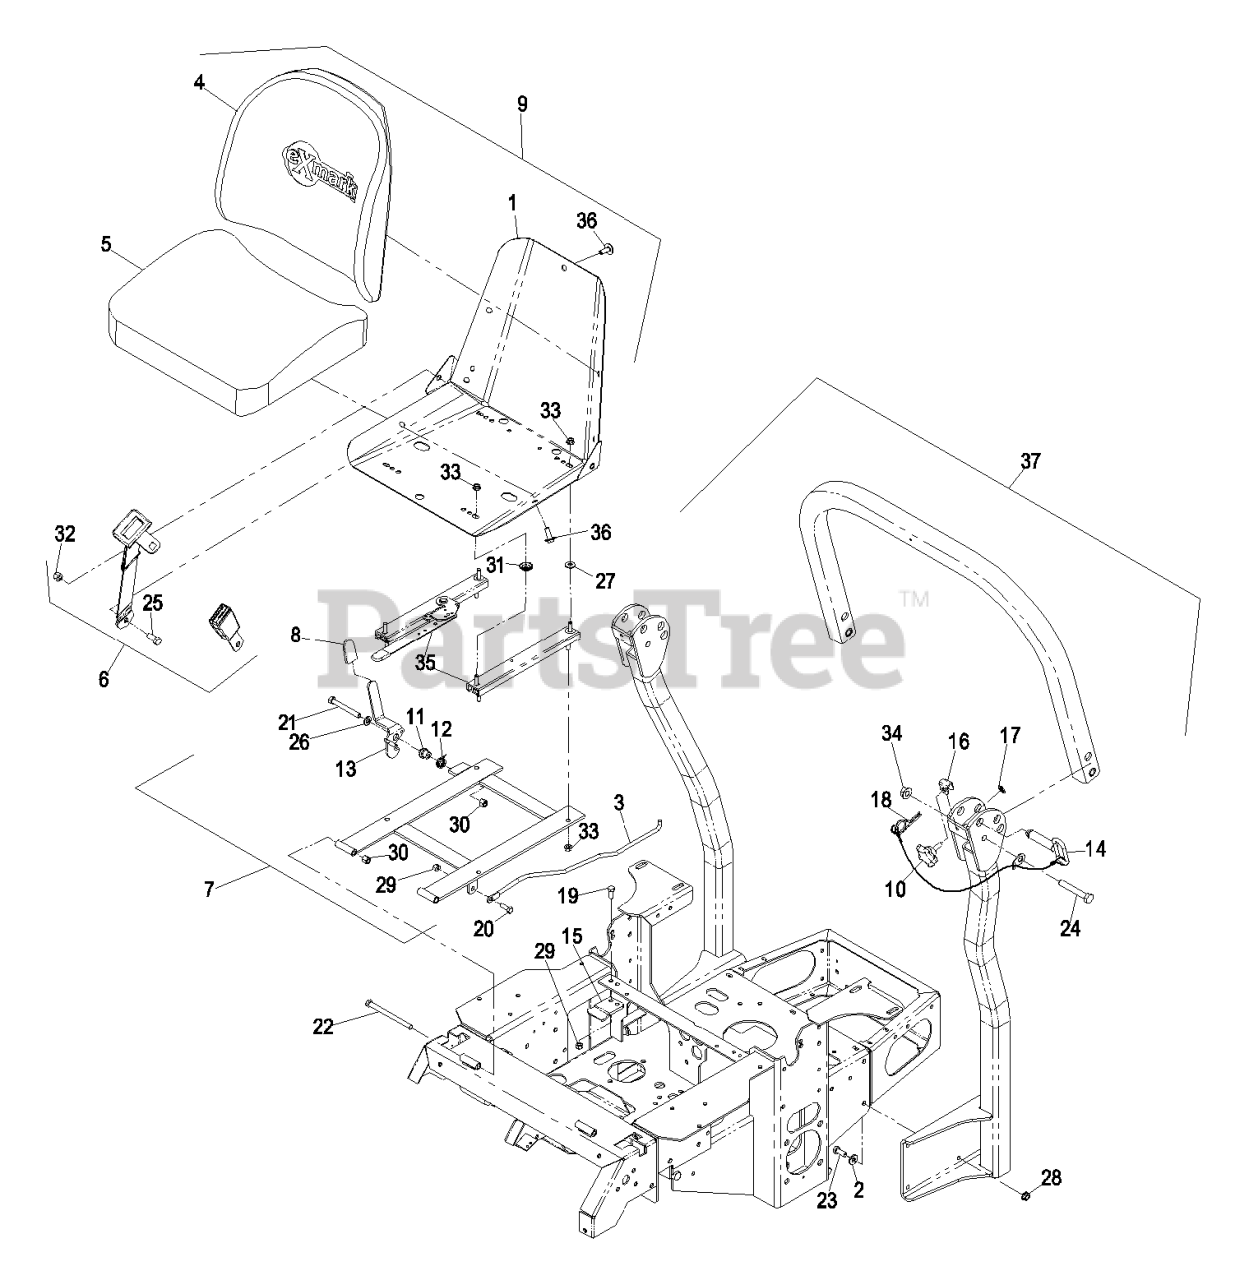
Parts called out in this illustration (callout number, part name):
1	FRAME-SEAT
2	WASHER-BELLEVILLE
3	ROD-RETAINER, SEAT
4	CUSHION,SEAT BACK
5	CUSHION,SEAT BOTTOM
6	SEATBELT KIT
7	ASM,SEAT FRAME
8	GRIP-LEVER
11	BUSHING-LATCH, SEAT
12	SPRING-TORSION
13	LATCH ASM
14	PIN-FOLD, ROPS
15	CATCH-LATCH, SEAT
17	NUT-PUSH
18	HAIRPIN
19	SCREW-HH
20	SCREW-HH
21	SCREW-HH
22	SCREW-HH
23	SCREW-HH
24	SCREW-HH
25	SCREW-HH
26	WASHER-FLAT
27	WASHER-FLAT
28	NUT-HHF, WHIZ
29	NUT-LOCK, NI
30	NUT-LOCK, NI
31	SPACER-TRACK
32	NUT-LOCK
35	TRACK-SEAT
36	BOLT-SEAT
37	KIT, LAZER HP / CT 2 POST
